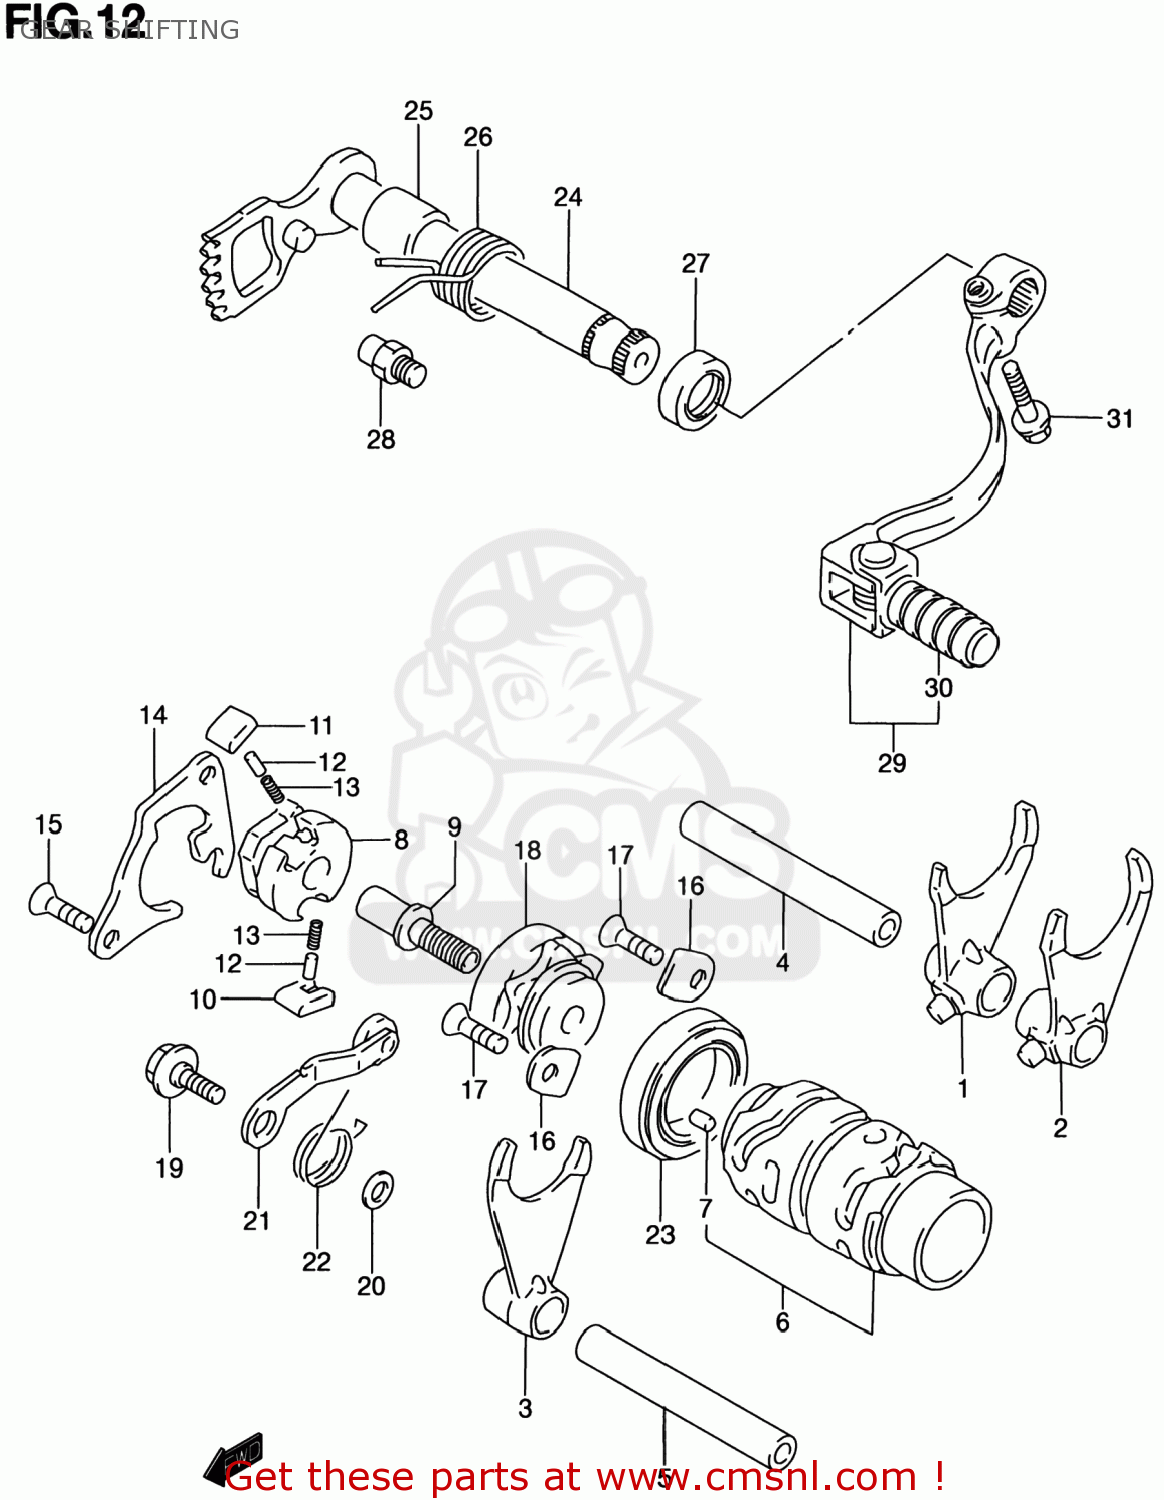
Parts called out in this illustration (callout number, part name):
1	FORK,GEAR SHIFT NO.1
2	FORK,GEAR SHIFT NO.2
3	FORK,GEAR SHIFT NO.3
4	SHAFT,GEAR SHIFT FORK NO.1
5	SHAFT,GEAR SHIFT FORK(L:60)
6	CAM,GEAR SHIFT
7	PIN
8	GEAR,GEAR SHIFT CAM DRIVEN
9	PIN,SHIFT CAM DRIVEN GEAR
10	PAWL,GEAR SHIFT NO.1
11	PAWL,GEAR SHIFT NO.2
12	PIN(5X8)
13	SPRING
14	LIFTER,GEAR SHIFT POLE
15	SCREW
16	RETAINER,COUNTER BEARING,R
17	SCREW
18	PLATE,SHIFT CAM STOPPER
19	BOLT(6X14.3)
20	WASHER
21	STOPPER,SHIFT CAM
22	SPRING
23	BEARING
24	SHAFT,GEAR SHIFT
25	SPACER(14X20X17.5)
26	SPRING
27	SEAL,OIL(14X22X6)
28	STOPPER,GEAR SHIFT CAM
29	LEVER ASSEMBLY,GEAR SHIFTING
30	RUBBER,GEAR SHIFT PEDAL
31	BOLT,G/S SWITC
